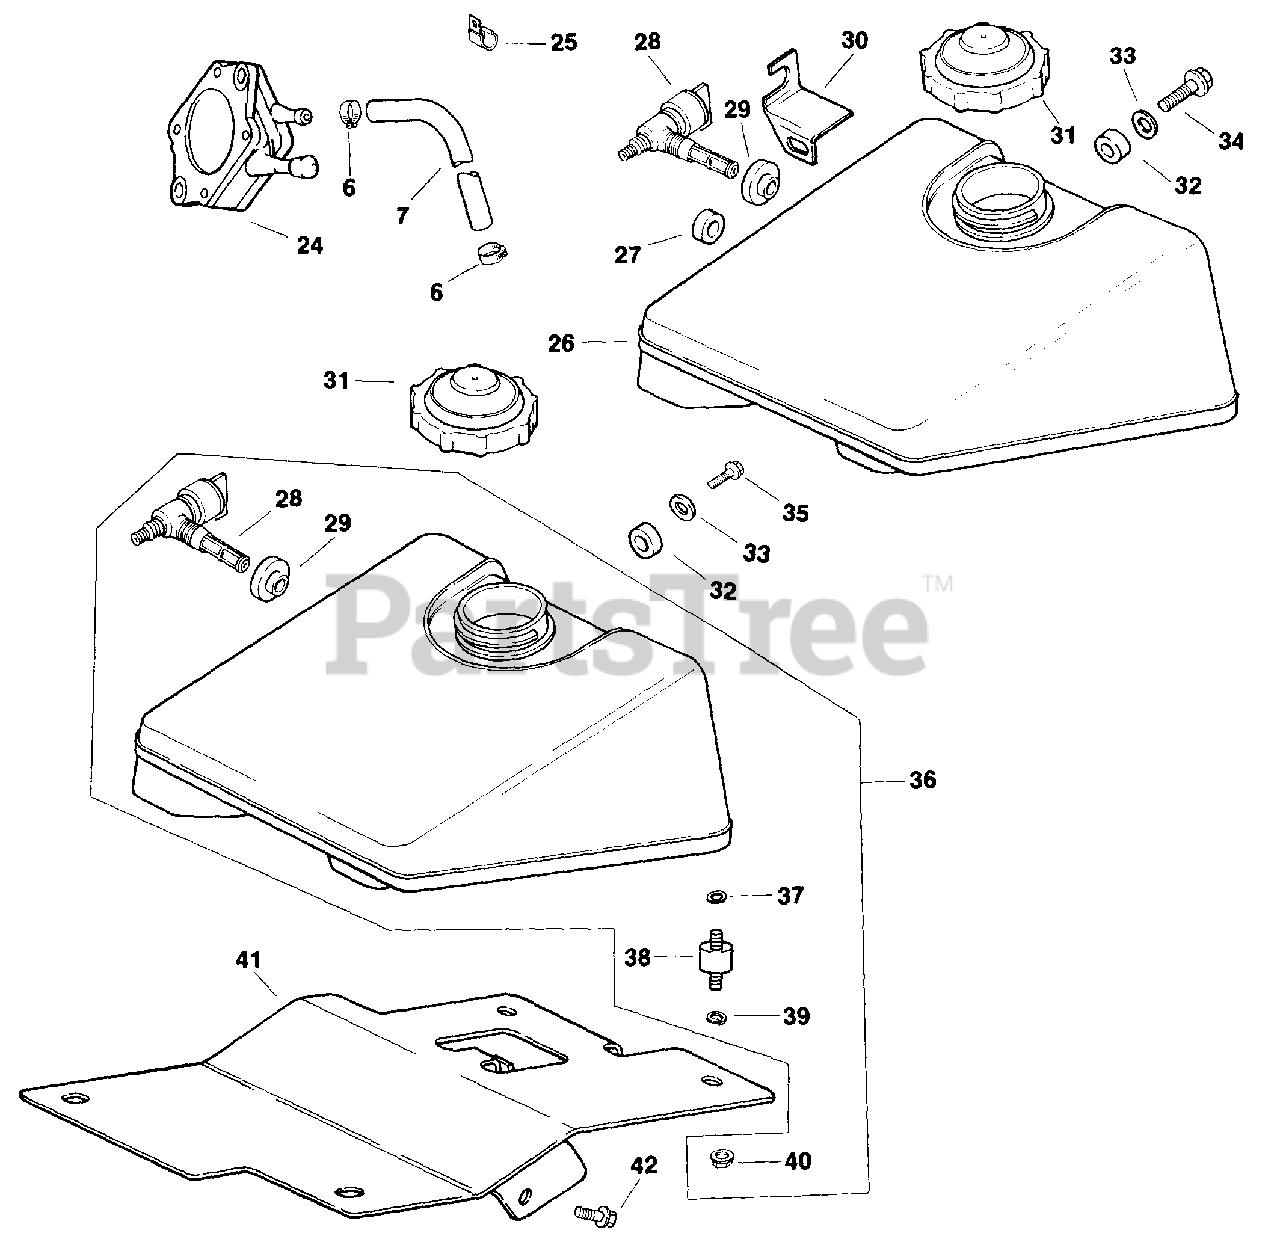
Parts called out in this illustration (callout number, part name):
28	VALVE, FUEL SHUT-OFF
29	BUSHING, FUEL TANK
34	Screw, tank mounting M8x1.25x25.5
36	KIT, FUEL TANK - DISC.
37	WASHER, FLAT 1/4" (O.D. 5/8")
38	MOUNT, ISOLATION
39	WASHER, INT TOOTH LOCK 1/4"
40	PALNUT, 1/4-20
41	BRACKET - USE 15 126 16
42	Screw, tank bracket - starter end
1511313-S	DECAL,FUEL VALVE SHUT-OFF-DISC.
2511313	DECAL - USE 15 113 16
